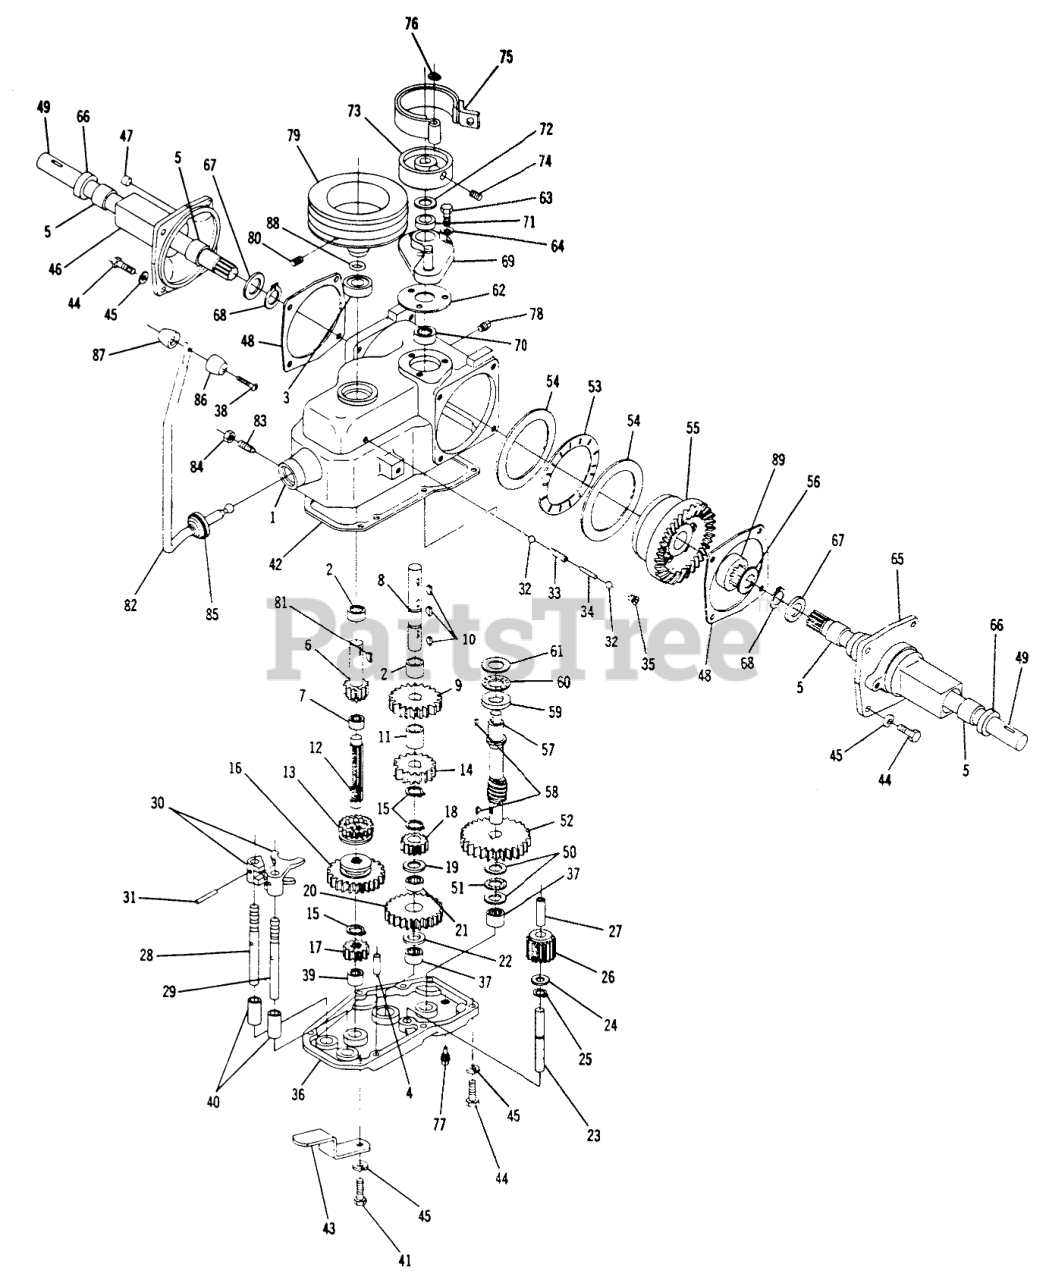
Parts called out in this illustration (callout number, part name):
1	Housing-Gear Case
2	BEARING-NEEDLE
3	BEARING-BALL
4	PIN-DOWEL
5	BEARING-NEEDLE
7	BEARING-NEEDLE
8	Shaft Idler
17	GEAR
18	52020/ITE 5HP SINGL
19	WASHER-THRUST
21	BEARING-NEEDLE
23	Shaft-Reverse Idler
24	51003 CORPORAL HVY
26	GEAR/BUSHING ASM-REVERSE IDLER
27	BUSHING
28	RAIL-SHIFT
29	RAIL-REAR SHIFT
31	PIN-ROLL
32	BALL-DETENT
34	PIN-SHIFT
37	BEARING-NEEDLE
38	Bolt #10-24 x 1 1/4
40	Bushing-Shifter Rail
41	Bolt 3/8-16 x 1
44	Bolt 3/8-16 x 1
45	Lockwasher
55	BULLT 325
58	KEY WOODRUFF
61	Rae-Thrust
63	Bolt 5/16-18 x
64	Lockwasher
65	Housing Axle L.H.
72	WASHER-THRUST
74	Screw 1/4-20 x 5/8
77	Plug 1/4 Pipe
80	Set Screw-Nylok
81	Key
83	SETSCREW
84	Nut 1/4-20
86	KNOB
87	KNOB
88	O-Ring
89	Bearing Axle
